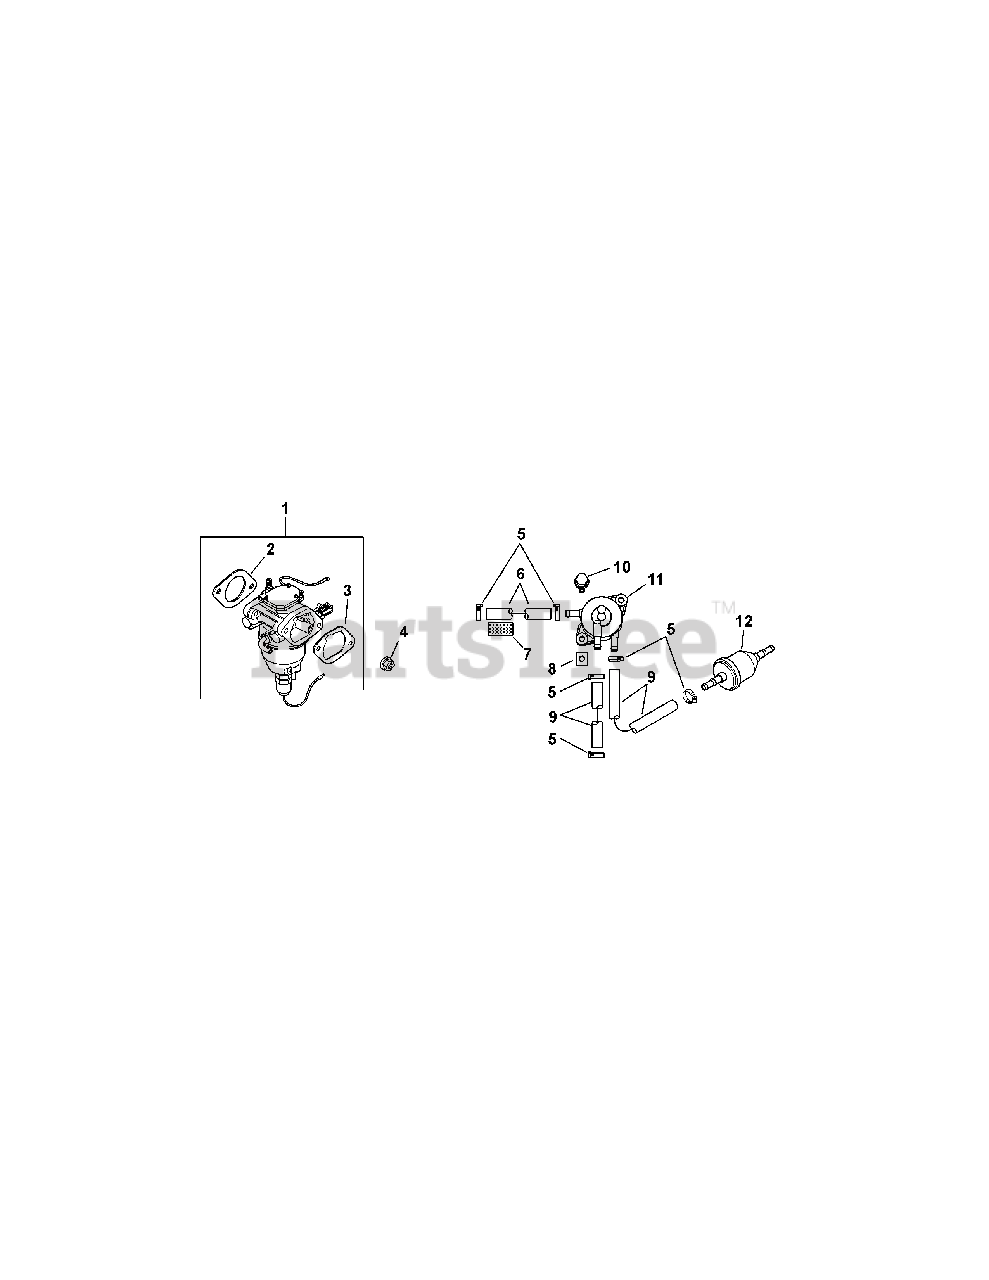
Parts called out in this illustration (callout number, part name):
1	KIT, CARBURETOR w/GASKETS (Includes 2,3)
2	GASKET, CARBURETOR
3	GASKET, AIR CLEANER BASE
4	NUT, FLG M6X1.0
5	CLAMP, HOSE 1/2''
6	LINE, FUEL 11'' (11" - fitting to pump)
7	SLEEVE, INSULATING 6.0", 0.5 I.D
9	LINE, FUEL (13" - pump to carb)
10	SCREW, TAP M6X1.7X18
12	FILTER,FUEL 51 MICRON (FUEL PUMP)
